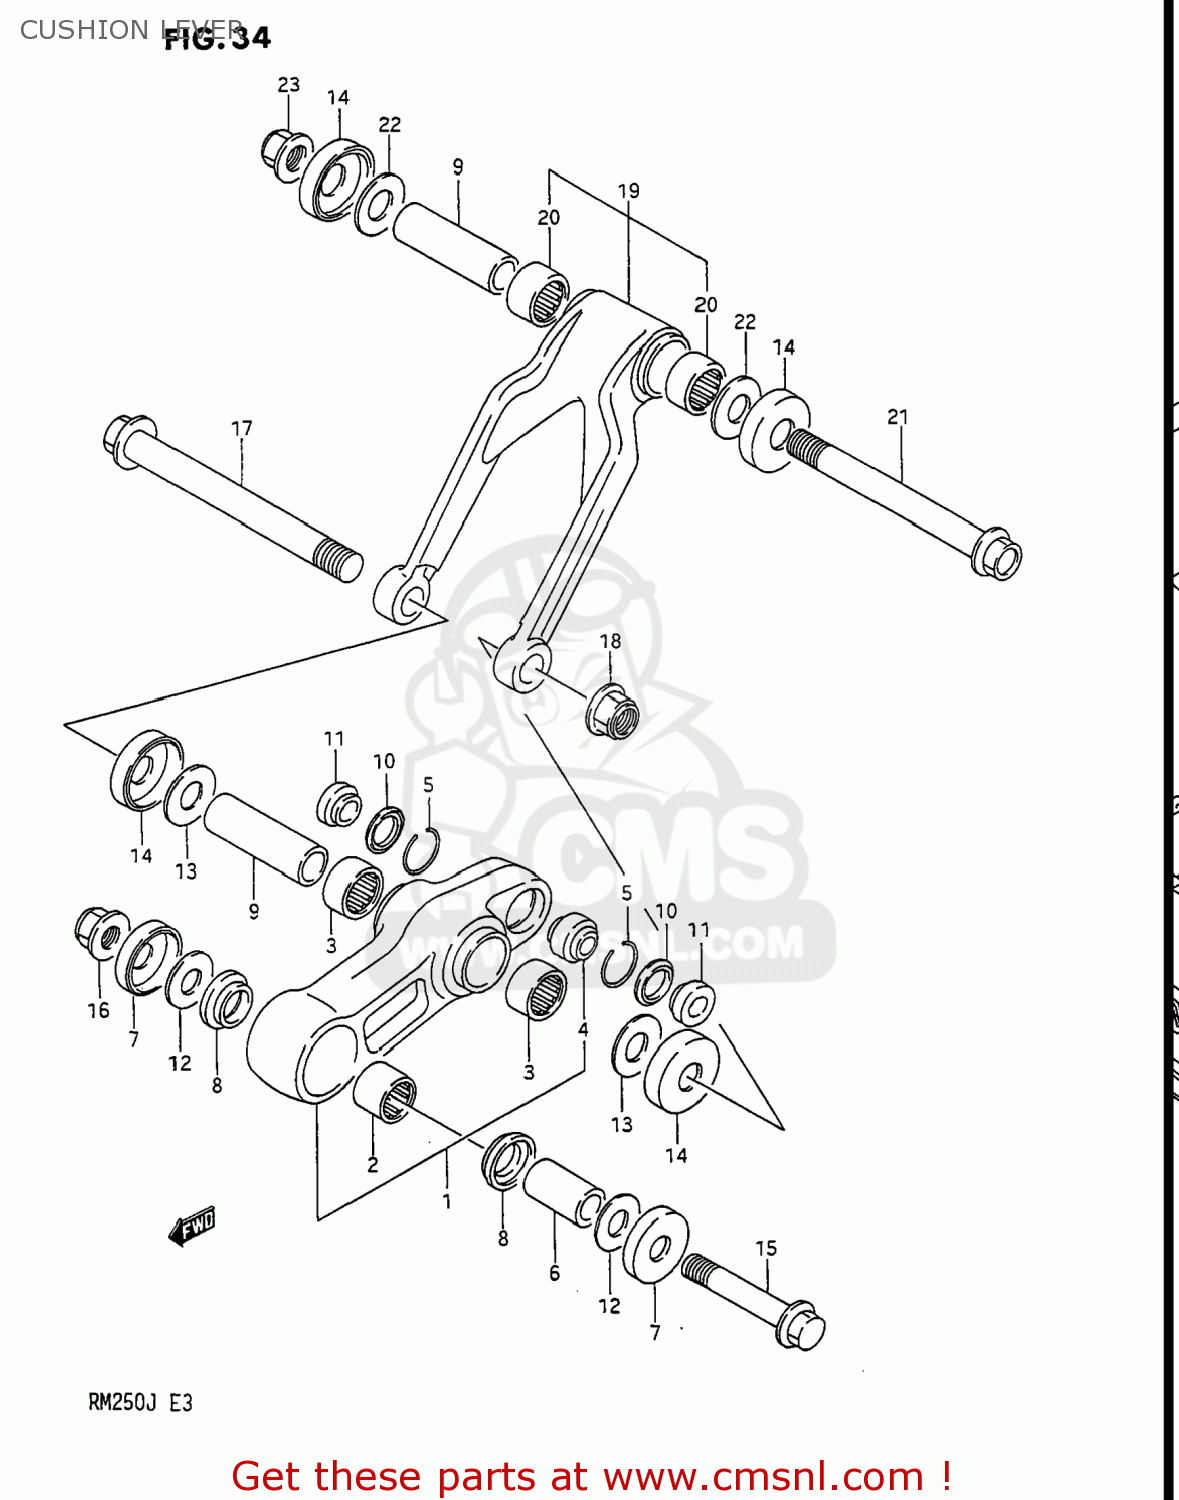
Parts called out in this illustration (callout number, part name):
1	LEVER SET,REAR CUSHION
2	BEARING(20X27X25)
3	BEARING(20X27X20)
4	BEARING,RR CUSHION LEVER
5	RING
6	SPACER,REAR CUSHION LEVER
7	COVER,REAR SWING ARM DUST
8	COLLAR,RR CUSHION LEVER FR
9	SPACER,REAR CUSHION LEVER
10	SEAL,DUST RR SHOCK ABSORBER
11	COLLAR
12	WASHER
13	WASHER
14	DUST SEAL,RR C
15	BOLT,RR CUSHION LEVER FR
16	NUT 12MM
17	SHAFT,RR CUSHION LEVER
18	NUT
19	LEVER SET,REAR CUSHION
20	BEARING(20X27X20)
21	BOLT,REAR CUSHION ROD
22	WASHER
23	NUT
